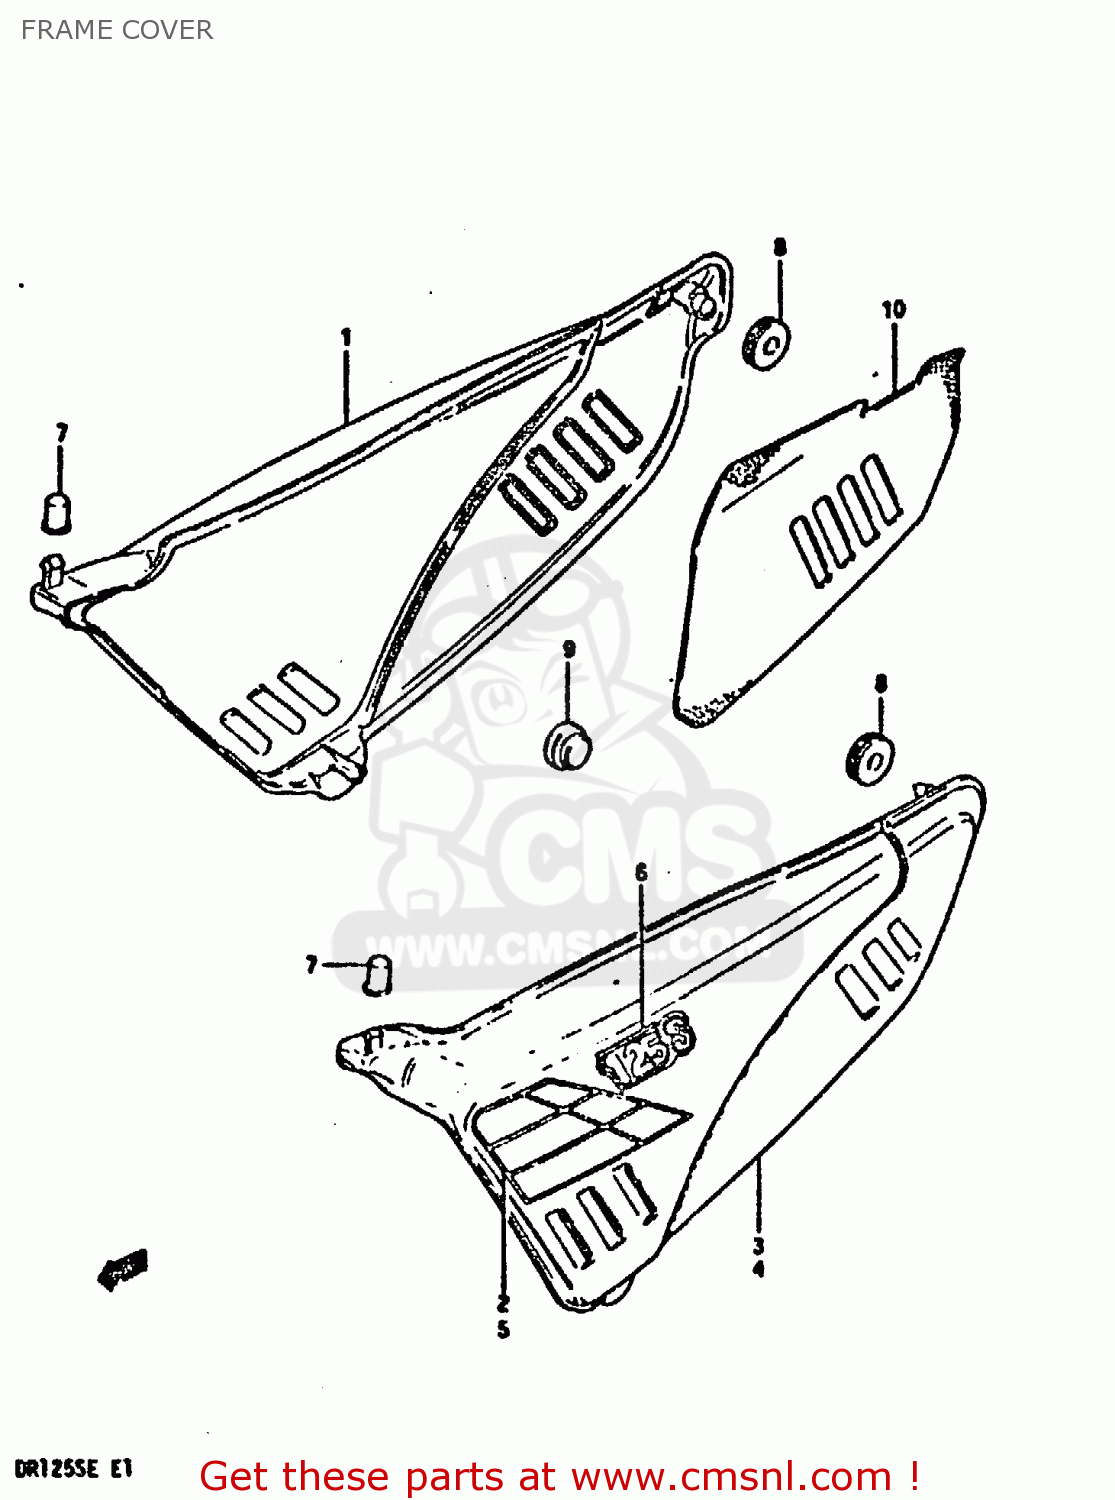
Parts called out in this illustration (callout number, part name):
1	COVER, FRAME RH (RED)
2	TAPE SET, FRAME COVER RH
3	COVER, FRAME LH (RED)
4	COVER, FRAME, LH
5	TAPE SET, FRAME COVER LH
6	EMBLEM
7	CUSHION
8	CUSHION
9	CUSHION
10	HEAT SHIELD,FRAME COVER
